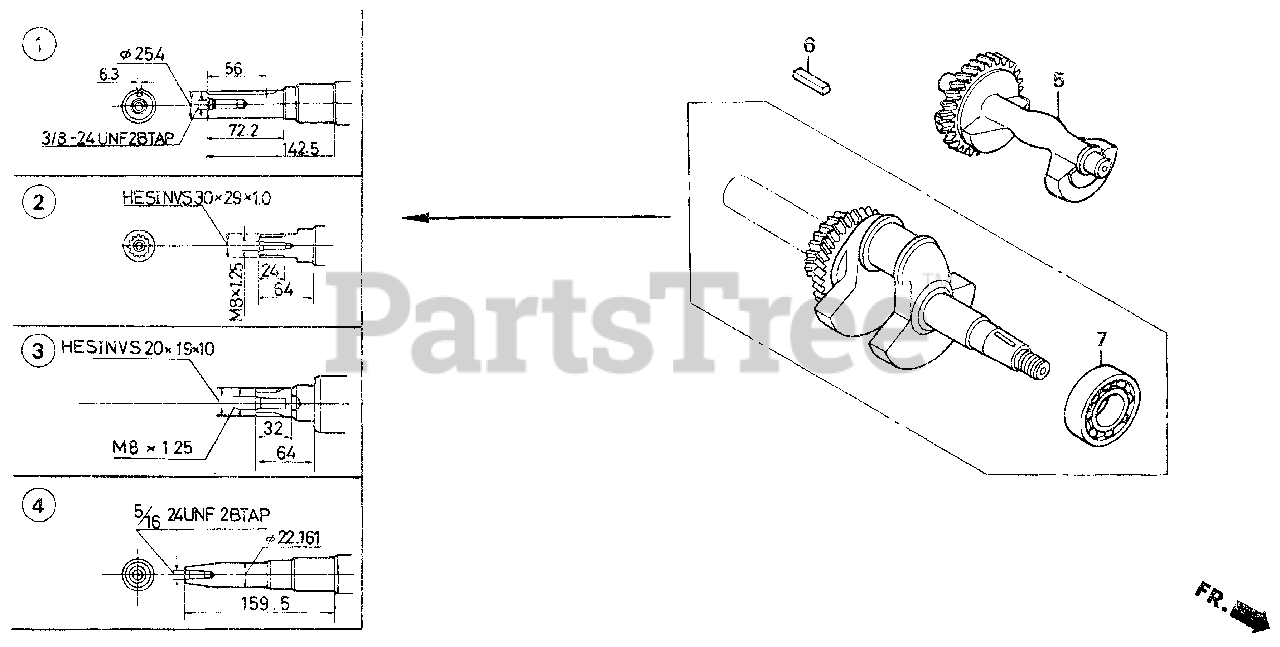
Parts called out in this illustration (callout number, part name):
1	CRANKSHAFT (Q-TYPE)
5	WEIGHT, BALANCER
6	KEY (6.3X6.3X43)
7	BEARING, RADIAL BALL (6207)
